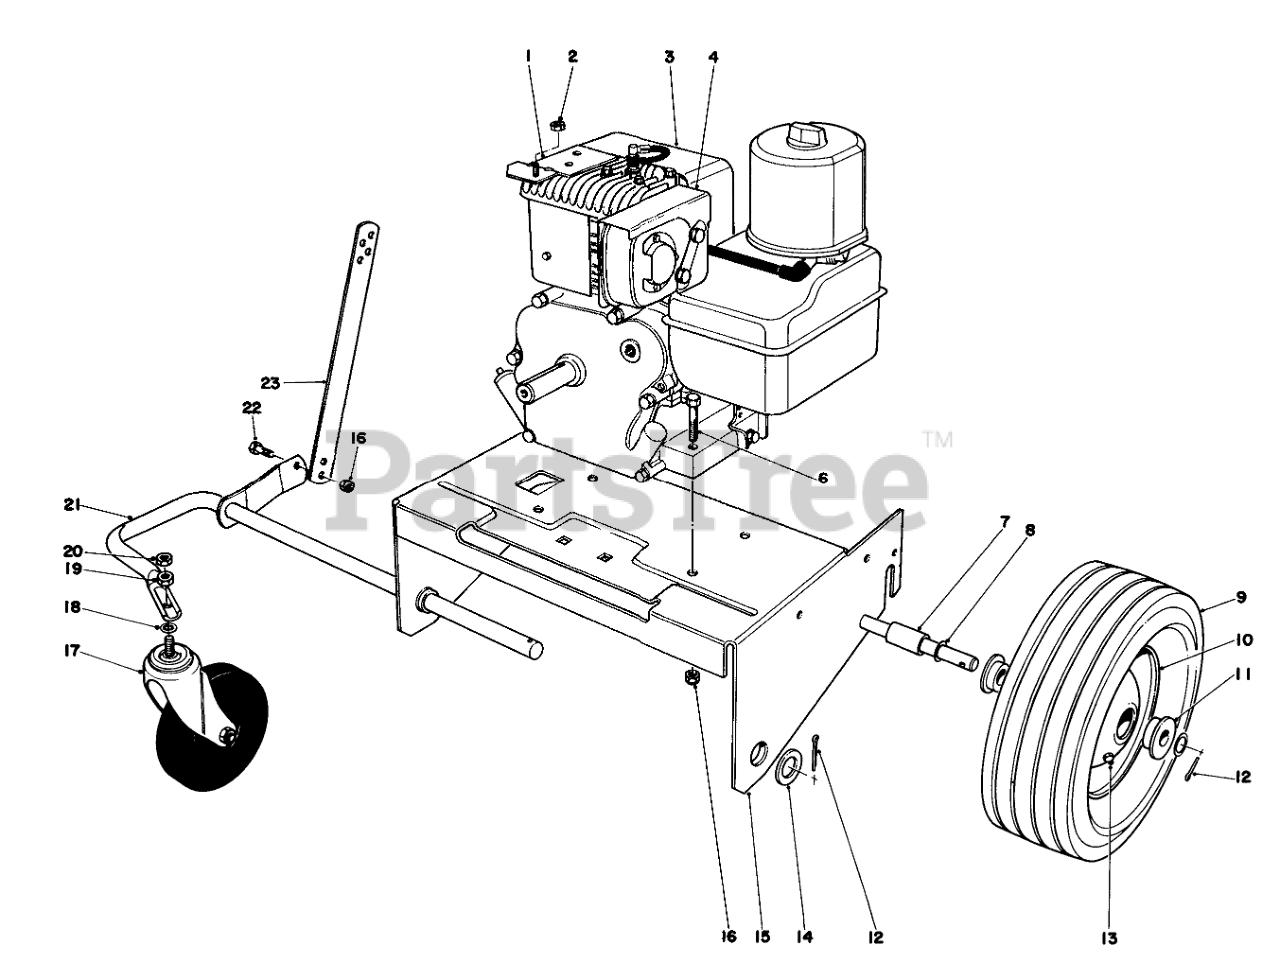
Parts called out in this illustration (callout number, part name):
1	MTG BRKT WA B
2	NUT-LOCK, NI
4	HEAT SHIELD
6	SCREW-HH
7	SPACER-AXLE
8	WASHER
9	3.50X10 SEMIPNEU TIRE
10	Wheel & Tire Assembly (Incl. Ref. #9, 11 & 13)
11	BUSHING
12	PIN-COTTER
13	FITTING-GREASE
14	WASHER-FLAT
15	BLWR ENG MTG PLT WA
16	NUT-LOCK, CONE
17	CASTER
18	WASHER-LOCK/INT
19	NUT-HH
20	1/2-13 CONELOCK NUT
21	FRT WHL SUPPORT WA
22	SCREW-HH
23	HT ADJ BAR
